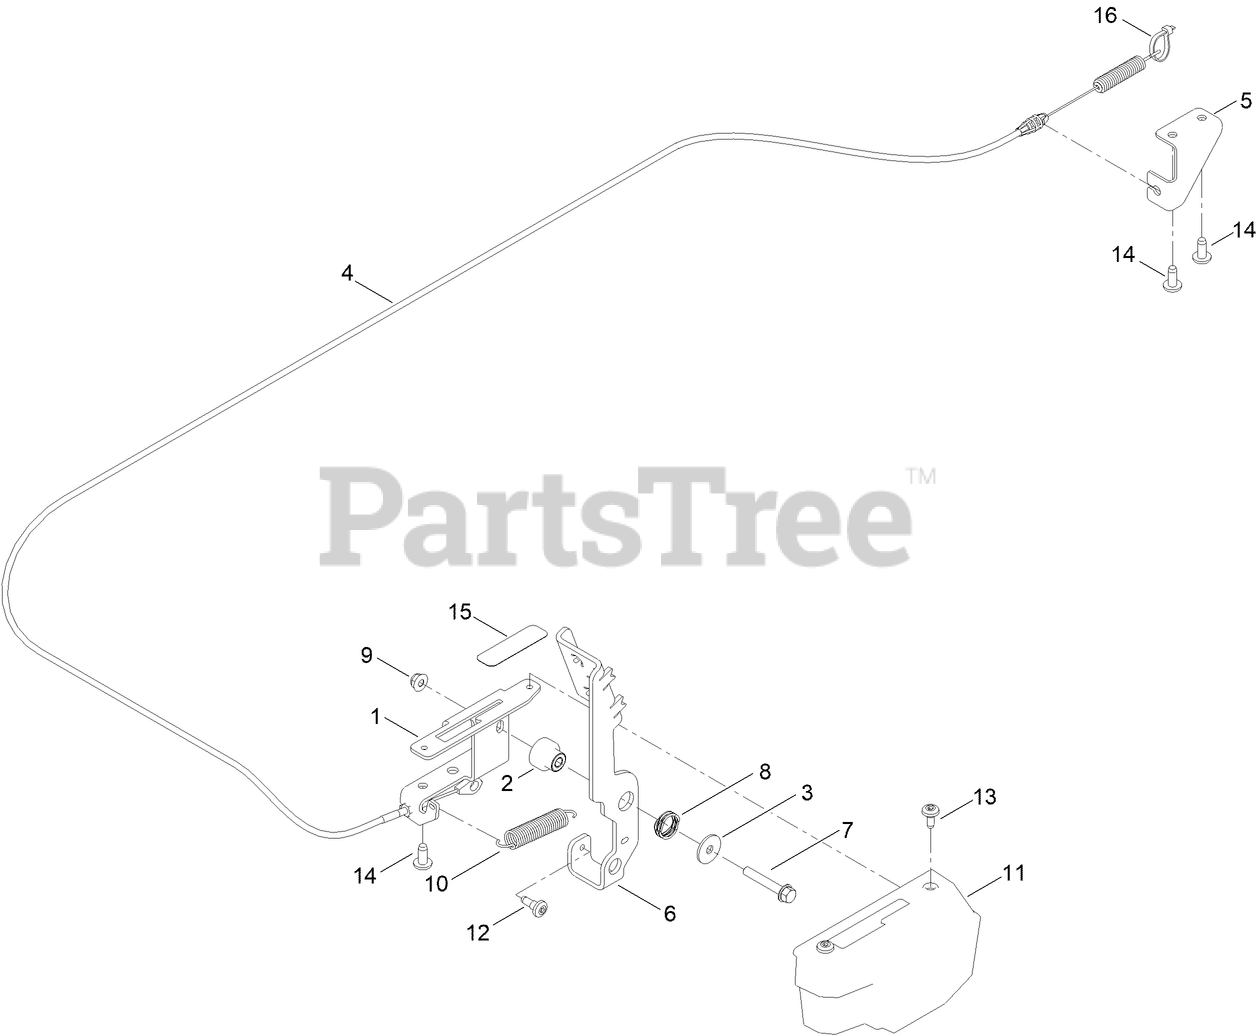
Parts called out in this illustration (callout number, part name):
1	BRACKET-PEDAL, BRAKE
2	BUSHING-FLANGE
3	WASHER-PIVOT
4	CABLE-BRAKE
5	BRACKET-CABLE, BRAKE
6	PEDAL-BRAKE
7	SCREW-HHF
8	WASHER-WAVE
9	NUT-HF
10	SPRING-PEDAL, RETURN
11	COVER-BRAKE, PARKING
12	SCREW-SHOULDER
13	SCREW-SHOULDER
15	DECAL-BRAKE, PARKING
16	TIE-CABLE
